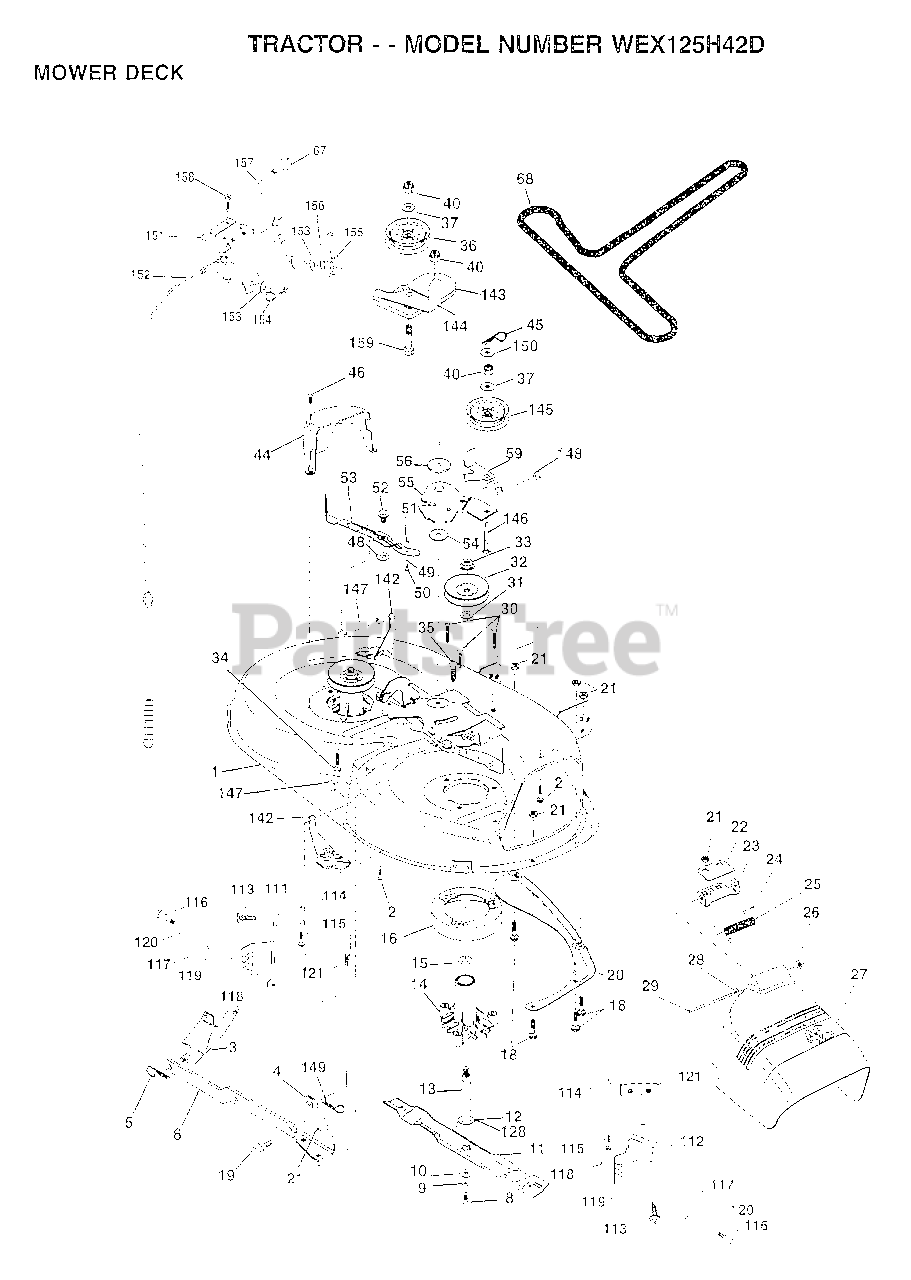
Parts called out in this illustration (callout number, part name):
1	MOWER DECK ASSY
2	BOLT
3	BRKT ASM SWAY BAR
4	BRACKET DECK
8	BLADE BOLT
10	WASHER.HARD.BLADE
11	"BLADE.42"" HIPERF"
12	BEARING.BALL
14	HSG ASM MANDREL
15	BEARING
16	STRIPPER RND MWR
18	BOLT
19	BOLT SHD 5/16-18
20	BAFFLE VORTEX 42
22	STIFFENER BRKT
23	DEFLECTOR BRKT
24	CAP-SLEEVE LT
25	SPRING TORSION
26	NUT PUSH M
27	SHIELD DEFLECTOR 42''
28	WASHER
29	HINGE ROD
30	"SCREW-THD ROLL,WA"
31	WASHER
32	PULLEY.MANDREL.42
34	BOLT
35	XMAS TREE FASTNER
36	FLAT IDLER PULLEY
37	WASHER
44	GUARD MAND LH BLK
45	RETAINER M
46	SCREW.1/4-20X5/8
48	HARD SMALL WASHER
49	ROLLER ASM-CAM
50	SHOULDER BOLT
51	LOCKNUT
52	BOLT.SHLD.5/16-18
53	BRAKE PAD ARM ASM
54	HARDENED WASHER
55	ARM-IDLER
56	SPACER.RETAINER.MOWER
59	GUARD IDLER TUV
67	KNOB T(3/8 HOLE)
68	BELT-V.SEC.46.KEL
111	BRACKET.GWHL.LH.
112	BRACKET.GWHL.RH.
113	SCREW
116	BOLT M
117	WHEEL.GAGE.BLK.PL
118	LOCKNUT
119	WASHER
120	WASHER
121	BRACKET.EXTRD.GWL
128	WASHER.FELT.
142	ARM SPRING BRAKE MOWER
143	BRACKET ARM IDLER
144	KEEPER BELT CLUTCH CABLE
145	PULLEY IDLER FLAT
146	BOLT
147	SPRING EXTENSION
148	SPRING RETURN IDLER
149	RETAINER SPRING
150	WASHER PM
151	BRKT CLUTCH CABLE
152	"CABLE.CLUTCH.42"""
153	WASHER FLAT
154	SPRING RETAINER
155	SPRING RETENTION LVR CLUTCH CAB
156	SPACER
157	ROD.CLUTCH.CABLE.3/8
158	SCREW LT
159	BOLT
